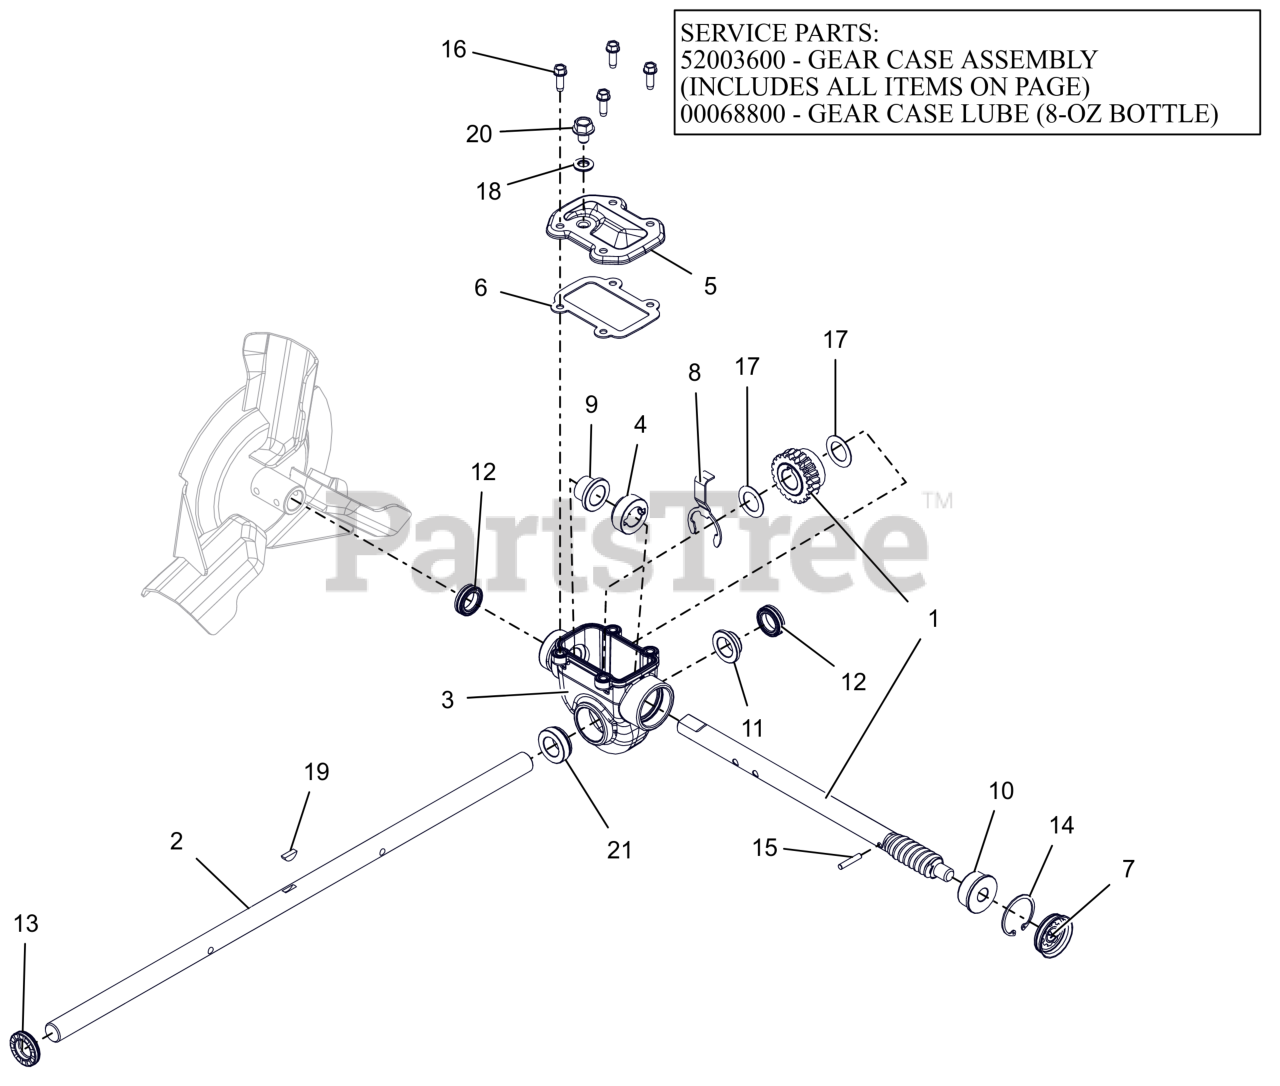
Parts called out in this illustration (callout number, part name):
1	SHAFT AND WORM GEAR ASSEMBLY
2	SHAFT, RAKE - 24" (.750 DIA)
3	GEARCASE, COMPACT ALUMINUM
3	GEAR CASE, 24" ALUM SM TOP-LD
3	ARIENS L3 LUBE, 8 OZ BOTTLE
4	THRUST COLLAR, .75" ID SLIPFIT
5	COVER, TOP - COMPACT
6	GASKET, TOP - COMPACT GEARCASE
7	COVER, GEAR CASE 1.50"
8	BUSHING RETAINER, COMPACT
9	BSHG-FLG .755X.878X.75X1.25
10	BSHG-FLG .503X1.303X.62X1.465
11	BSHG-FLG .755X.878X.424X1.25
12	SEAL-OIL .748X1.125X.312 TBC29
13	SEAL-OIL .748X1.300X.250 TBC29
14	RG-RTNG-INT 1.500X.050
15	PIN-STR .188X1.00 6150
16	SCR,TAP .25-20X.75 HWH TR ZCC
17	WSHR, FLT .760X1.225X.032 ZCC
18	WSHR-BND-SEAL .38X.75X.11 GALV
19	KEY-WDRF .19X.63 HRD #61
20	SCR,TAP .38-15X.50 HWH ROLOK
21	BSHG-FLG COMPACT, RIGHT
